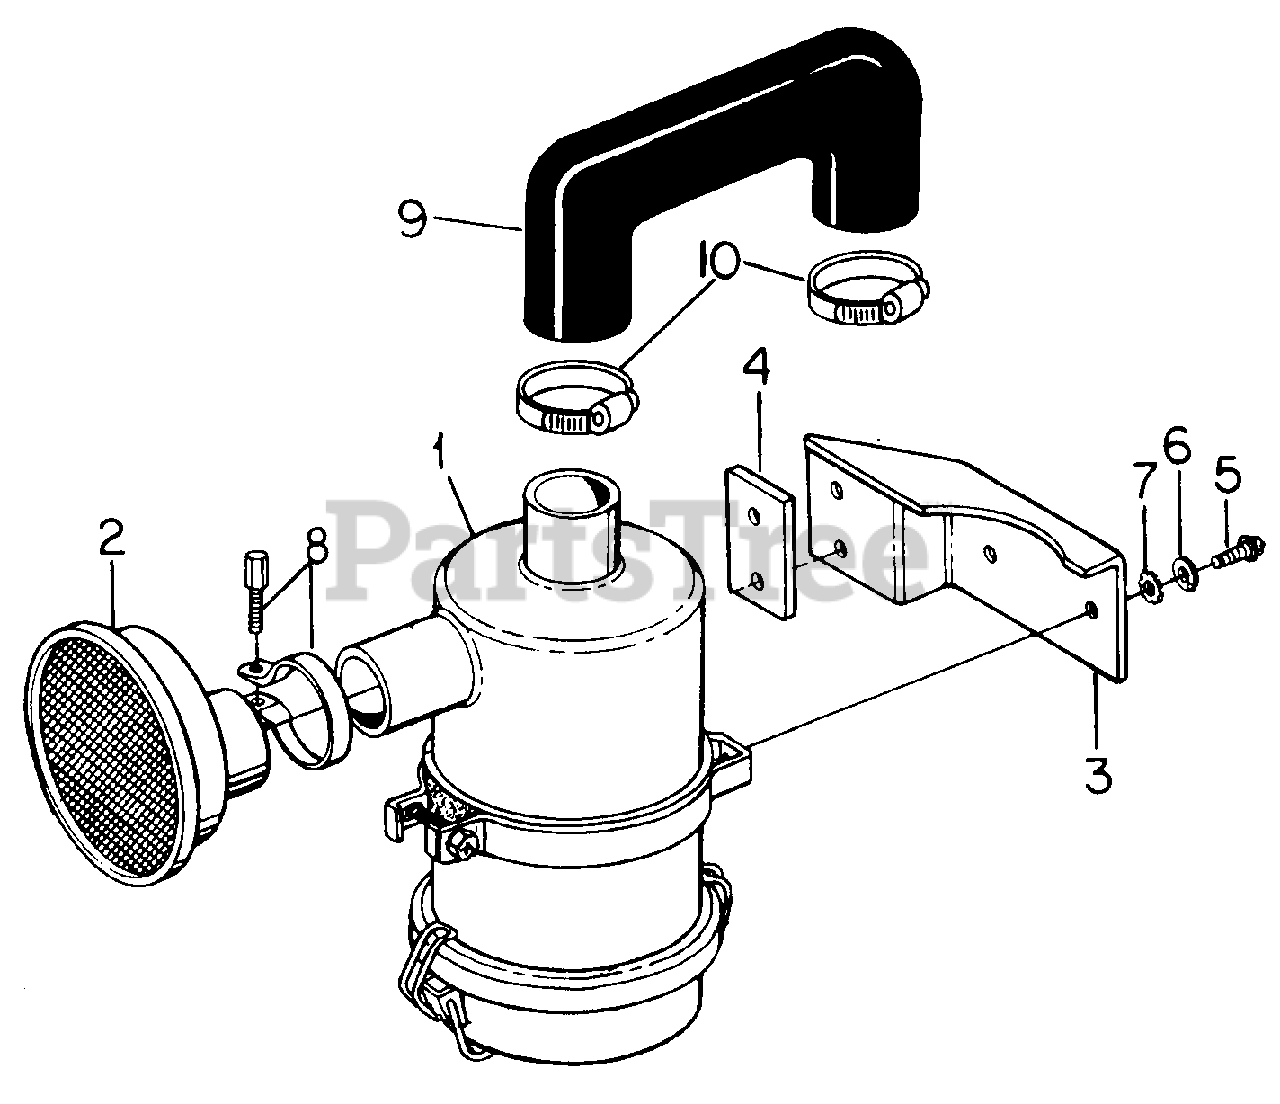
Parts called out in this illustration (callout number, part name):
1	Cleaner Assy, Air
2	Intake Assy, Air
3	Bracket, Air Cleaner
4	Pad, Isomount
5	Bolt, M8 X 20 Phc Class 8.8
6	Washer, 5/16 Lock
7	Washer, 5/16 Ext-Int Tooth Lock
8	Clamp, Air Cleaner Screen
9	Hose, Air Cleaner to Intake Manifold
10	Clamp, Air Cleaner Hose
